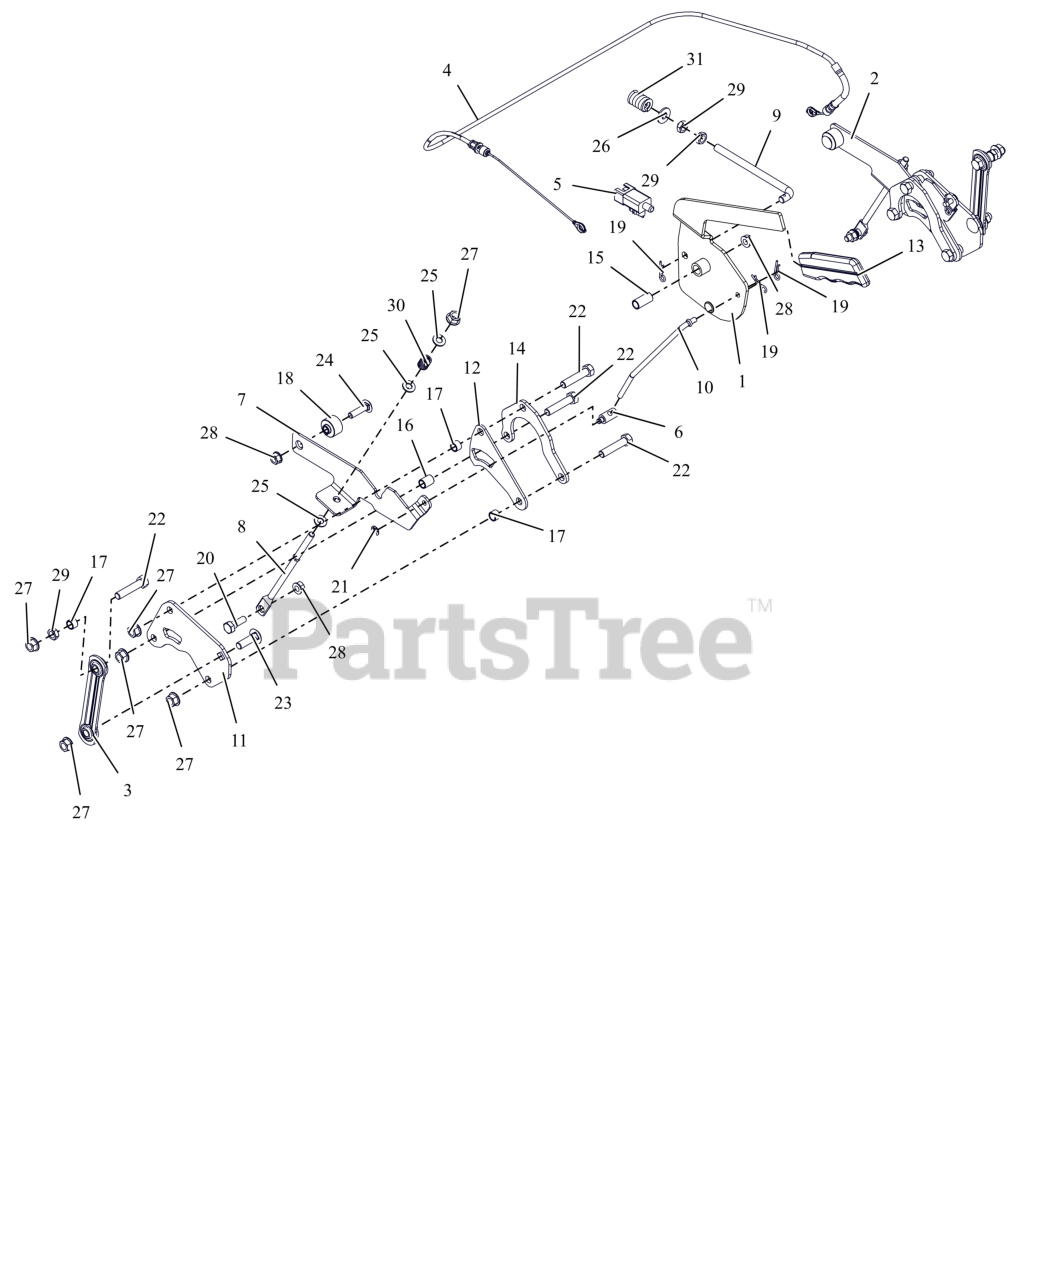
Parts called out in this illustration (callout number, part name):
1	LEVER, PARKING BRAKE
2	ARM, BRAKE - LH (W/PIN)
3	LINK, STAMPED STEERING
4	CABLE, BRAKE - PARKING
5	SWITCH, SNAP IN - N.O./N.O.
6	TRUNION, 1/4-20
7	ARM, BRAKE-RH
8	ROD, LINK - TRANSMISSION BRAKE
9	ROD, OVER CENTER
10	ROD, BRAKE LINK
11	BRKT, TRANSAXLE STEERING
12	BRKT-SPACER
13	GRIP, PARKING BRAKE (YELLOW)
14	PLATE, REAR REINFORCING
15	BSHG-SLV .385X.500X1.045
16	SPCR, SLV .385X.500X.652
17	SPCR, SLV .385X.500X.350
18	SPCR, FLANGE
19	PIN, HAIR #213 .08X1.19 ZCC
20	BOLT,SHLDR .38X.25 -.31-18X.75
21	RG-RTNG-EXT .250X.025
22	BLT, HEX .38-16X1.75 G5 ZCC
23	BLT,RHSSN .38-16X1.25 G5 ZCC
24	BLT, RHSSN.31-18X1.25 G5 ZCC
25	WSHR,FLT .344X.688X.065 ZCC
26	WSHR,FLT .375X.875X.083 ZCC
27	NUT-LK-TOP-FLG .38-16 ZC120
28	NUT-LK-TOP-FLG .312-18 GF ZCC
29	NUT-JAM .375-16 G2 ZCC
30	SPRING, COMPRESSION
31	SG-COMP .187X.56X1.62
